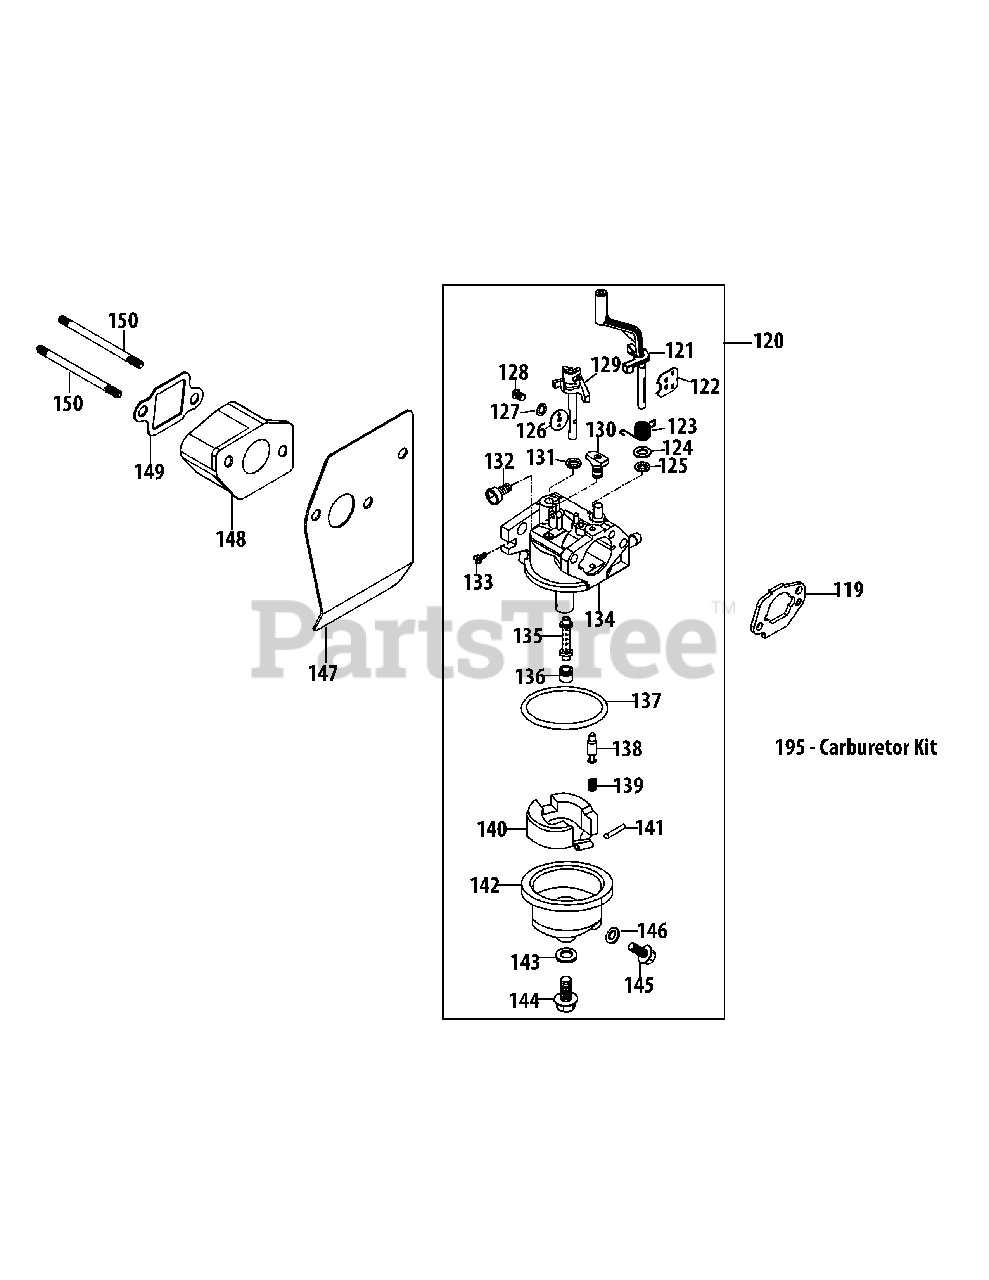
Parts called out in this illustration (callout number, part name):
119	Carburetor Gasket Plate
120	Carburetor Assembly
121	Choke Shaft
122	Choke Plate
123	Choke Return Spring
124	Choke Shaft Washer
125	Choke Shaft Fiber O-Ring
126	Throttle Plate
127	Throttle Plate Lock Washer
128	Screw M3X5 Throttle Plate
129	Throttle Shaft
130	Idle Jet Assembly
131	Throttle Shaft Fiber O-Ring
132	Idle Speed Adjusting Screw
133	Idle Mixture Screw
134	Carburetor Body
135	Emulsion Tube
136	Main Jet
137	Fuel Bowl O-Ring
138	Needle Valve
139	Needle Valve Spring
140	Float
141	Float Pin
142	Fuel Bowl
143	Fuel Bowl Gasket
144	Fuel Bowl Mounting Bolt
145	Fuel Drain Plug
146	Fuel Drain Plug Gasket
147	Carburetor Gasket
148	Carburetor Insulator
149	Carburetor Insulator Gasket
150	Carb Stud M6X92
195	Carburetor Kit -Major
